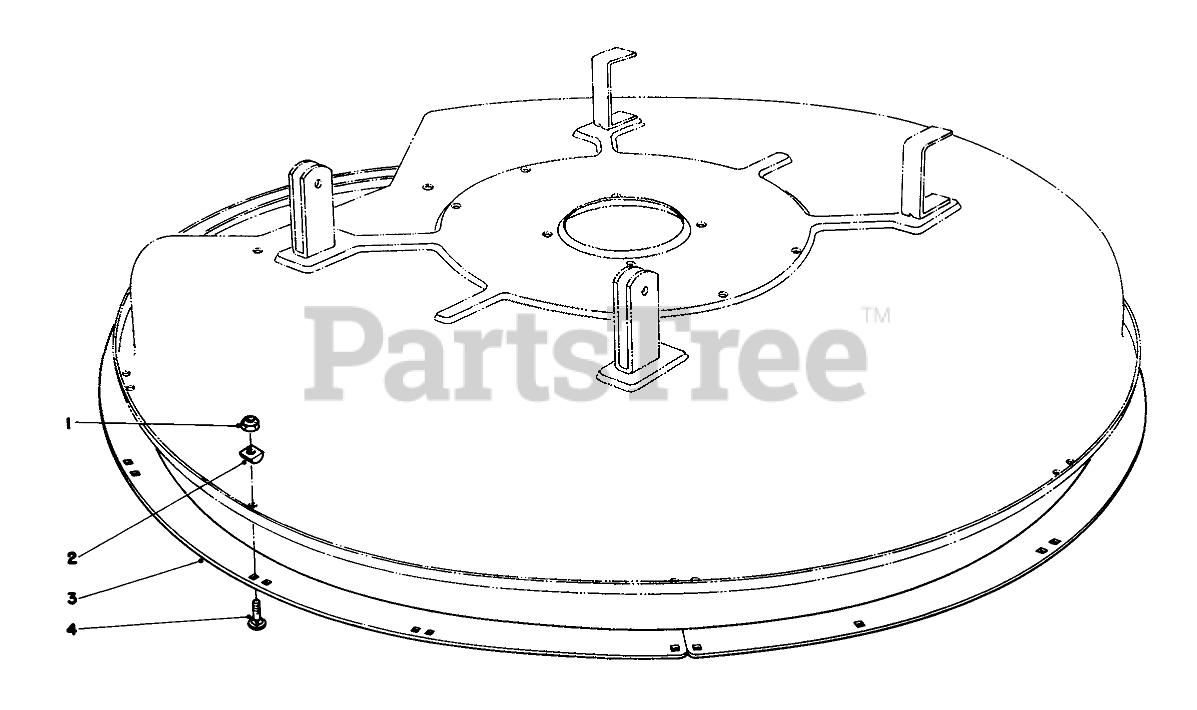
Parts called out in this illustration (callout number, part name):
1	NUT-LOCK, NI
2	Spacer-Deck Ring
3	DECK RING B
4	BOLT-CARR
